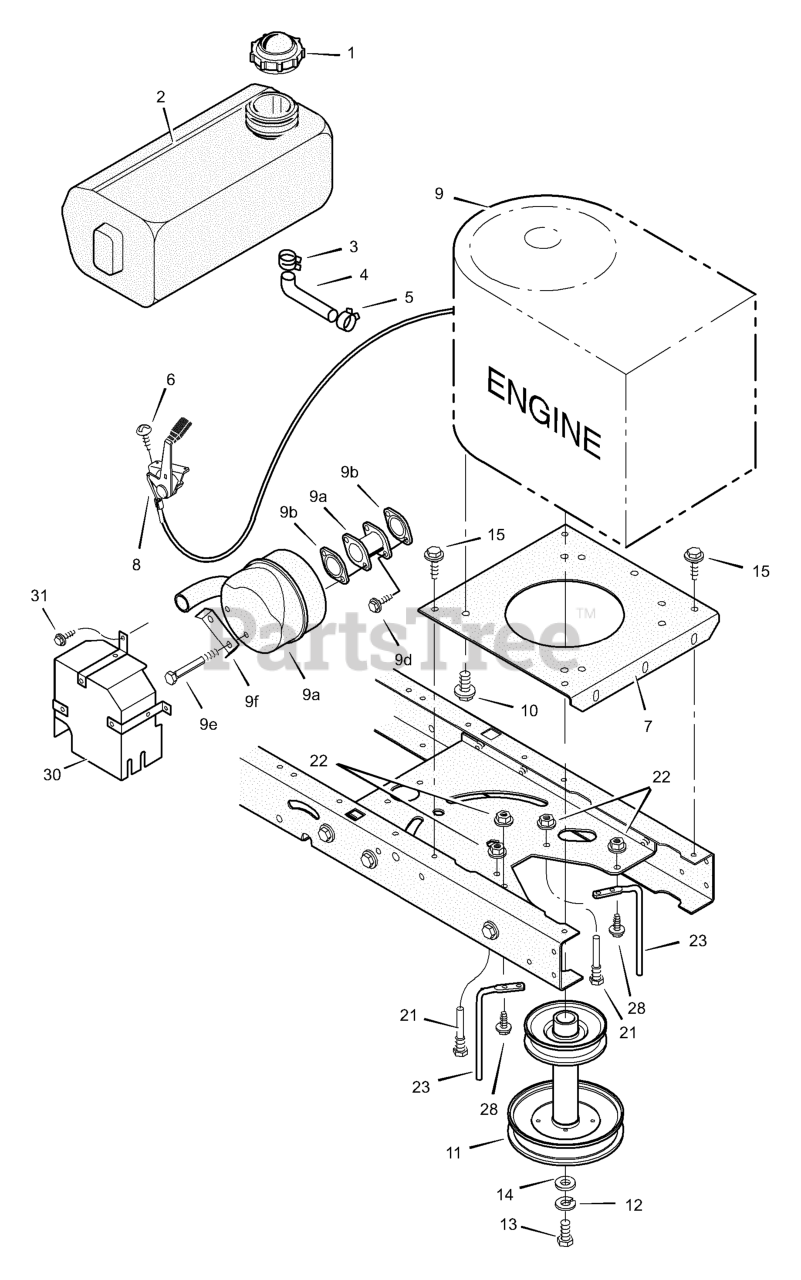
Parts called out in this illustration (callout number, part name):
1	Fuel Cap
2	Fuel Tank
3	Hose Clamp
4	Fuel Line (Must cut to length)
5	Hose Clamp
7	Plate, Engine
8	Throttle Control
9	Engine *
9A	Muffler
9B	GASKET, Exhaust
9C	Adapter, Muffler
9D	Screw, Adapter
9E	Bolt, Muffler
9F	Lock, Screw
10	Bolt, Engine Mount
11	STACK PULLEY ASSEMBLY
12	Lockwasher
13	Bolt, Hex
21	Guide, Belt
22	Nut, Flange
23	Guide, Belt
28	Screw
30	Shield, Heat
